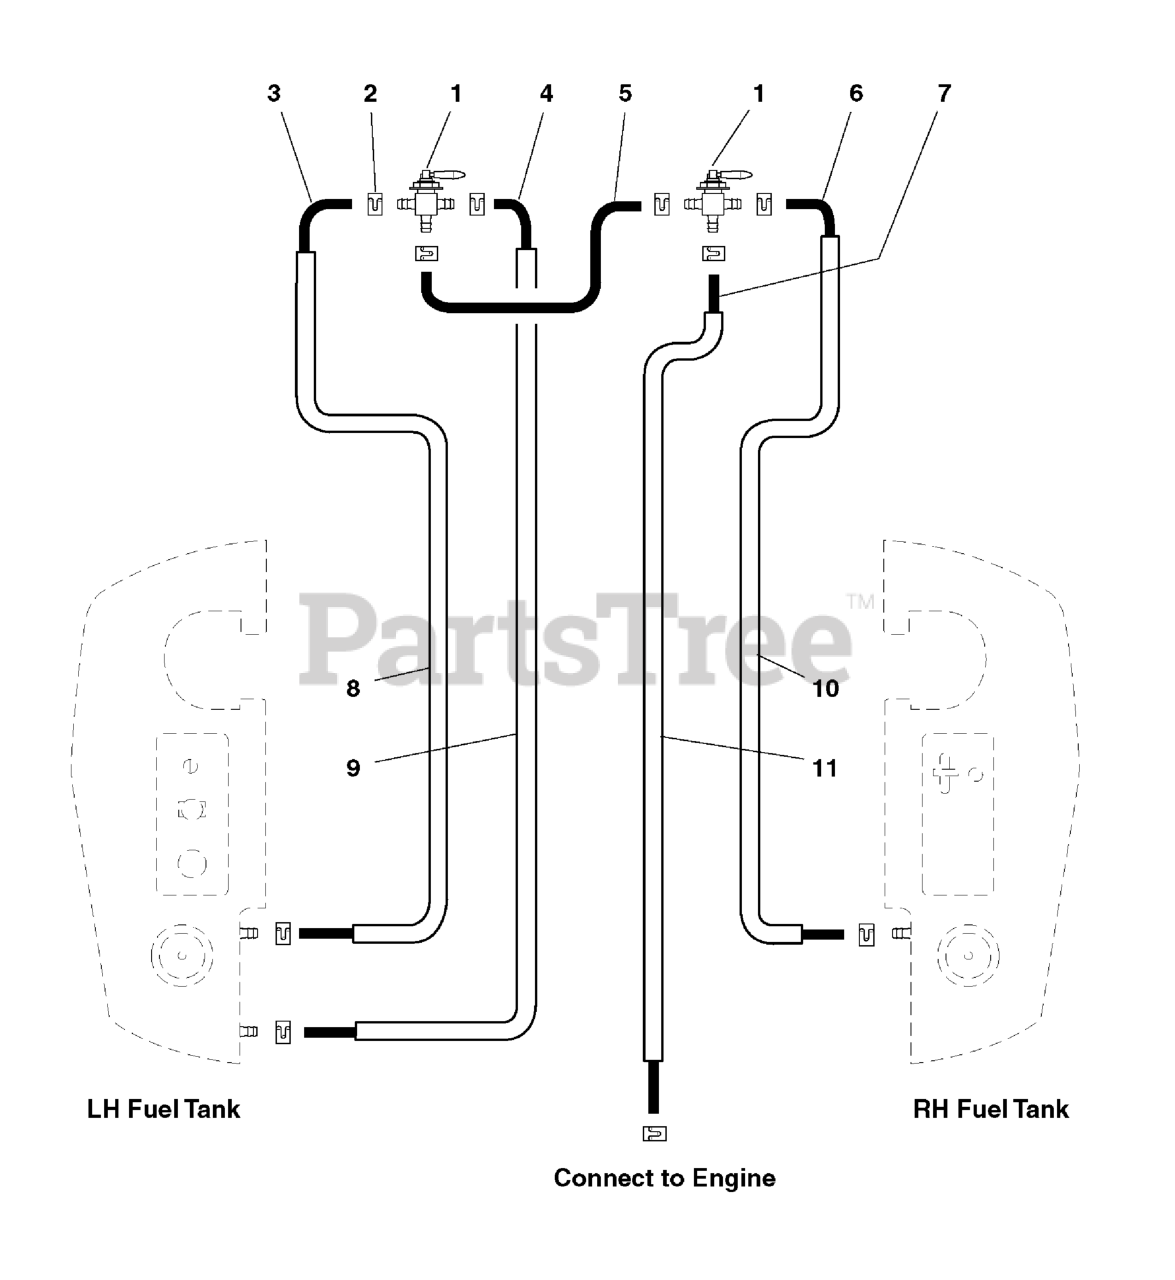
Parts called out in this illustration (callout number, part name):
1	VALVE, Fuel Shut Off
2	CLAMP, Hose
3	1/4" Fuel Line, 54" Long
4	1/4" Fuel Line, 56" Long
5	1/4" Fuel Line, 7-1/2" Long
6	1/4" Fuel Line, 45" Long
7	1/4" Fuel Line, 51" Long
8	WIRE LOOM, 53"
9	WIRE LOOM, 55"
10	WIRE LOOM, 44"
11	WIRE LOOM, 50"
